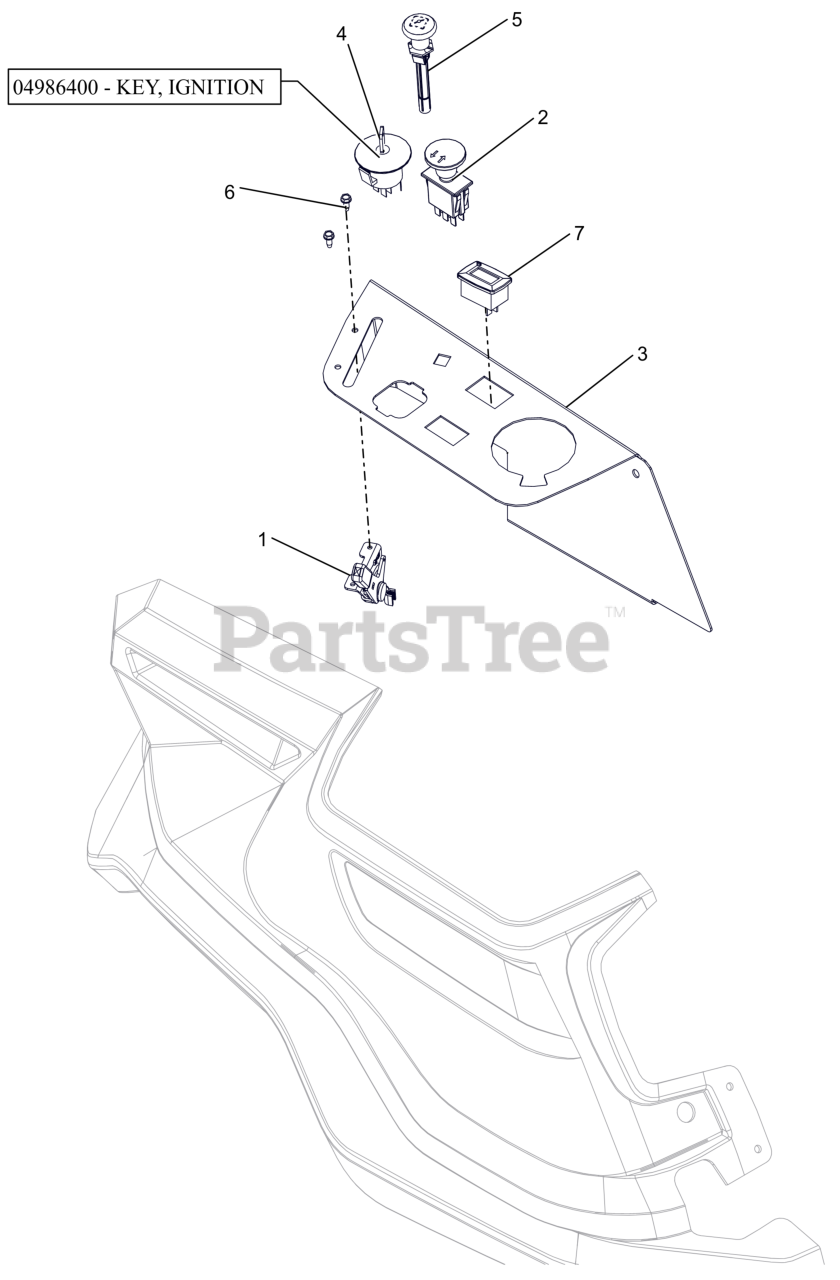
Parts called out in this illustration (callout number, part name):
1	CABLE - THROTTLE CONTROL
2	SWITCH, CLUTCH (YELLOW)
3	PANEL, RIGHT SIDE FENDER MOUNT
4	KEYSWITCH-IGNITION 4 POS
4	KEY, IGNITION
5	CABLE - CHOKE, SNAP-IN
6	SCR,TAP #10-24X.50 HWH TR ZCC
7	METER, HOUR W/MAINTENANCE
